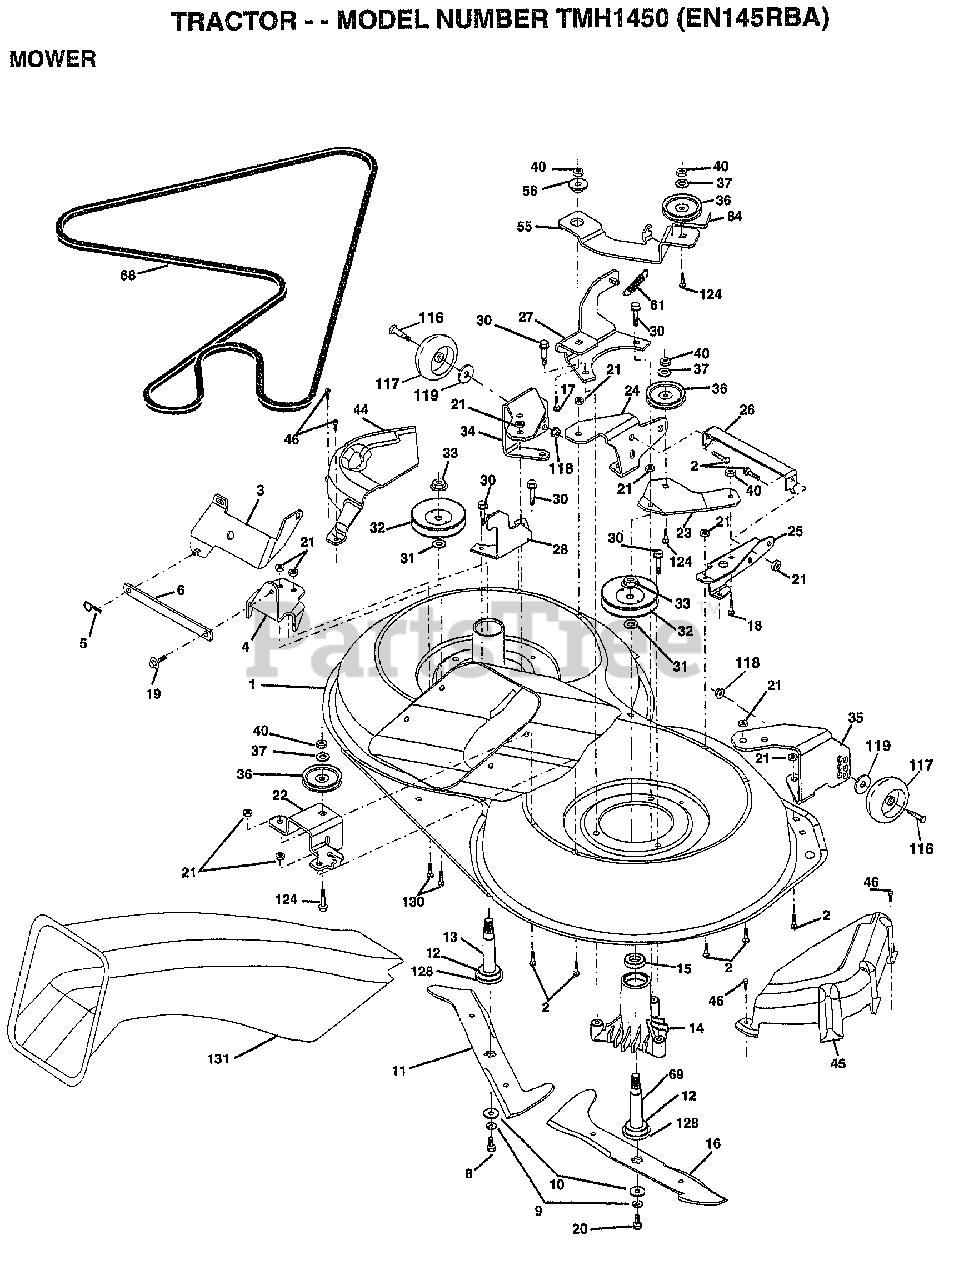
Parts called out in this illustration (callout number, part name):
1	HOUSING.ASM.MOWER
2	BOLT
3	BRKT.ASM.S-BAR.CHASSIS
4	BRKT.BAR.SWAY.DECK
6	BAR.SWAY.92.CRD
8	BLADE BOLT
10	WASHER.HARD.BLADE
11	BLADE.3-1.LH.92.CRD
12	BEARING.BALL
14	HSG ASM MANDREL
15	BEARING
16	BLADE.3-1.RH.CRD.92
17	BOLT.3/8-14X1.25
18	BOLT D
19	BOLT SHD 5/16-18
20	BOLT.3/8-24X1.25
22	BRKT.IDLER.SPRT.CRD
23	"BRKT.IDLER.SPRT.RF.92,CRD"
24	BRKT.SUSP.LF.92.CRD
25	BRKT.SUSP.RF.92.CRD
26	BRACE.SUPT.SUSP.FRT.CRD
27	BRKT.ASM.SUSP.RR.92.CRD
28	BRKT.ASM.SUSP.LR.92.CRD
30	"SCREW-THD ROLL,WA"
31	WASHER
32	PULLEY.MAND.36/46
34	BRKT.GUAGE.WHL.LF.92.CRD
35	BRKT.GUAGE.WHL.RF.92.CRD
36	PULLEY.IDLER.4.25
37	WASHER
44	COVER.MANDREL.LH.92.CRD
45	COVER.MANDREL.RH.92.CRD
46	SCREW.1/4-20X5/8
55	ARM.IDLER.92.CRD
56	SPACER RETAINER
61	SPRING.TENSION.BELT
68	HEX-BELT.92.MWR.105AA
69	SHAFT.ASM.W/LWR.BRG.RH.THD
84	"KEEPER-BELT,IDLER"
116	BOLT.SHOULDER
117	WHEEL GAGE DONUT
118	LOCKNUT
119	WASHER
124	BOLT.3/8-16X1.50
128	WASHER.FELT.
131	CHUTE.BAGGER.CRD
